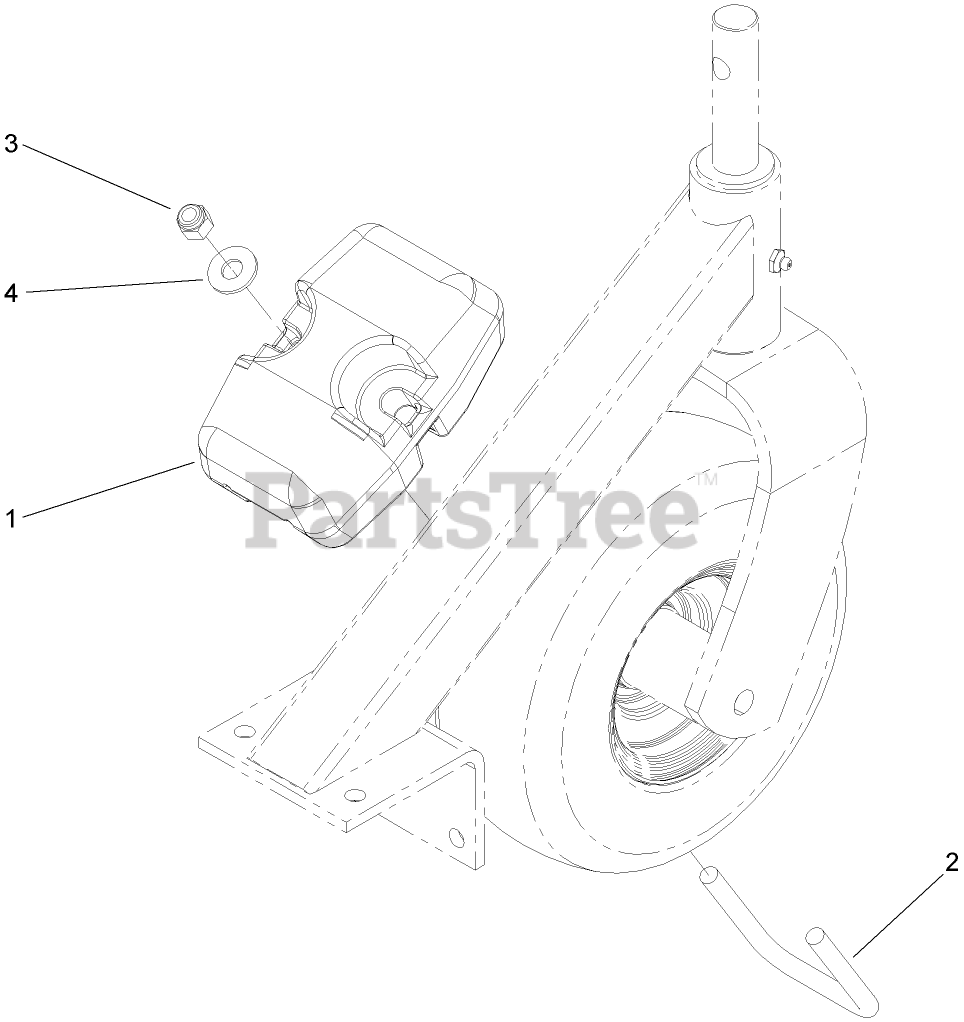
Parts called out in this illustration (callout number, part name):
1	WEIGHT-CASTER
2	U-BOLT
3	NUT-LOCK, NI
4	WASHER-FLAT
